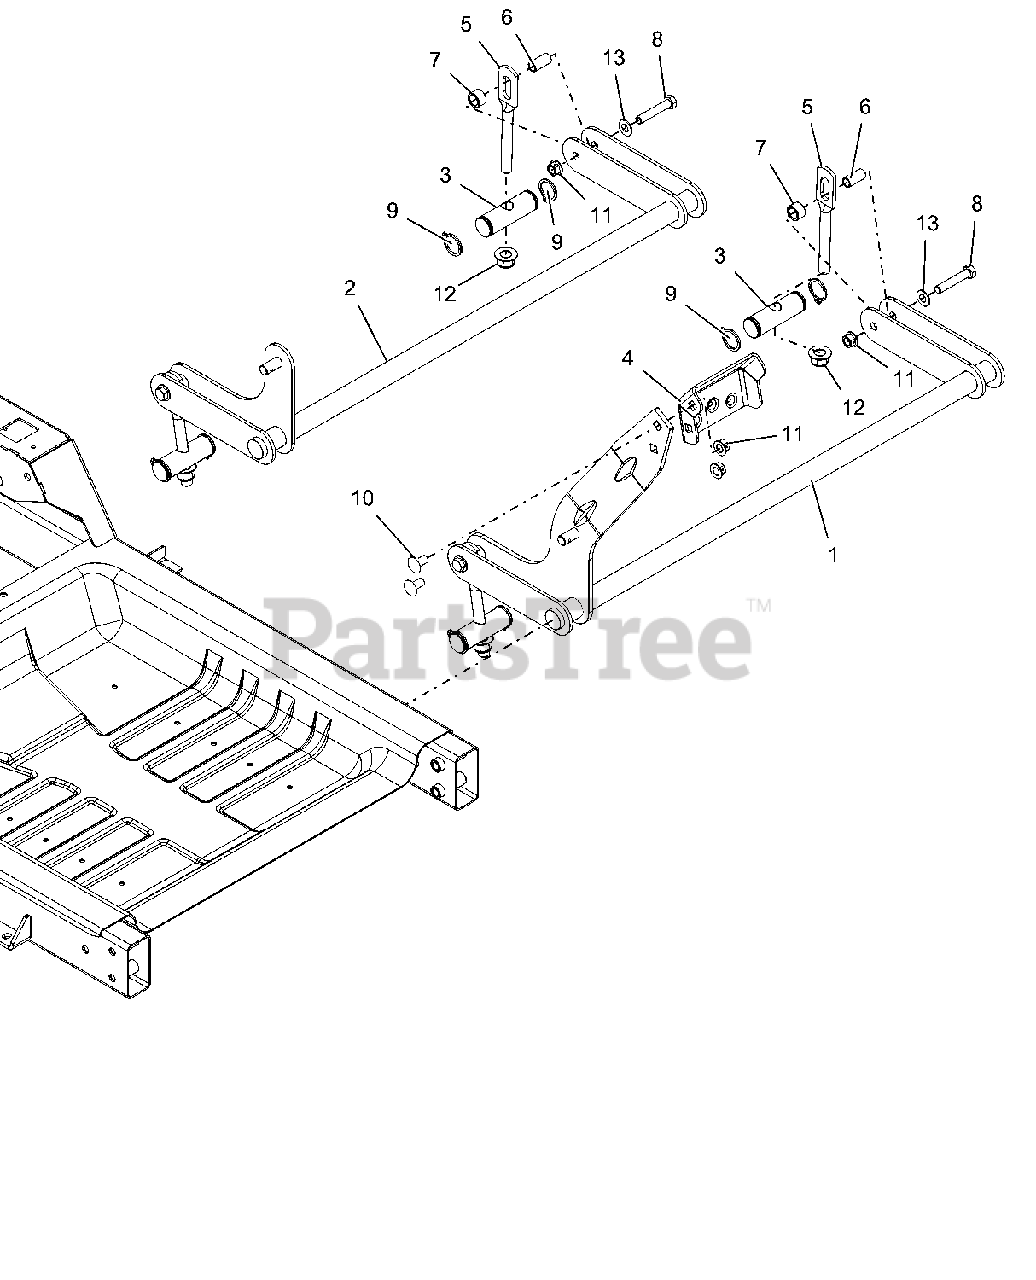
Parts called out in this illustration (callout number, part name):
1	WLDMT, FRONT DECK PIVOT
2	WLDMT, REAR DECK PIVOT
3	SHAFT, DECK LINK PIVOT
4	PEDAL, DECK LIFT (BOLT ON)
5	LINK, DECK (LONGER)
6	BSHG-SLV .385X.500X1.045
7	BSHG-SLV .510X.751X.475
8	BLT-HEX .38-16X2.00 GR8 YWZC
9	RG-RTNG-EXT 1.00X.078
10	BLT,RHSN .38-16X.75 G5 BFP
11	NUT-LK-CTR-FLG .38-16 YWZC
12	@NUT-LK-NYL-FLG .50-13 YWZC
13	@WSHR-FL-STL.406X.812X.065 YWZ
